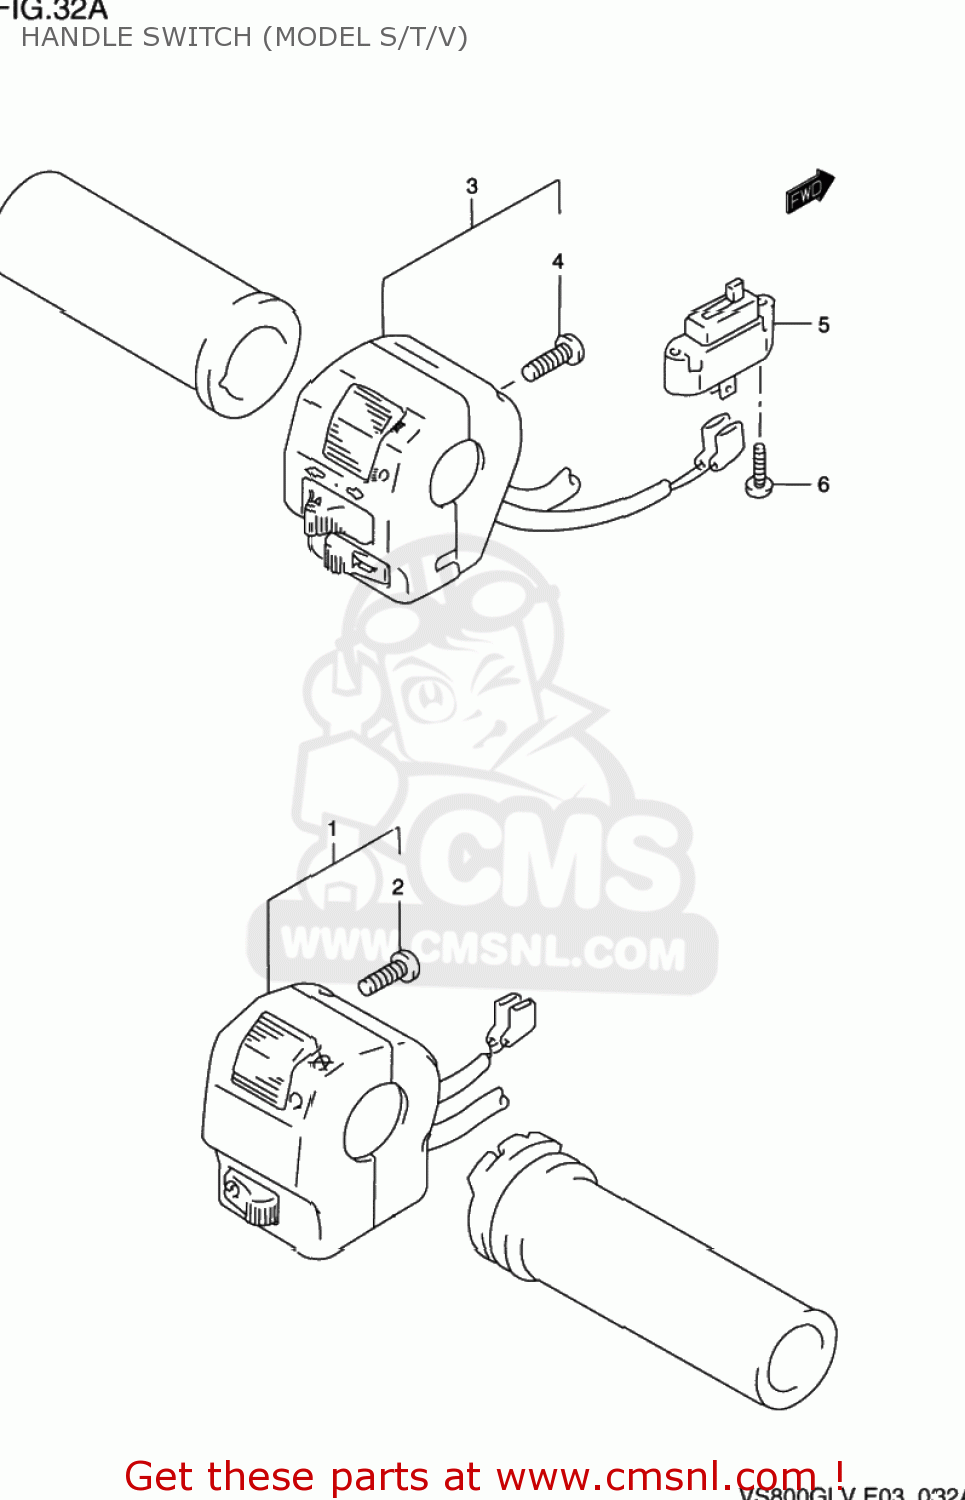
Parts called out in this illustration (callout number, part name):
1	SWITCH ASSY,HANDLE,R
2	SCREW
3	SWITCH ASSY,HANDLE,L
4	SCREW
5	SWITCH ASSY,CLUTCH
6	SCREW
